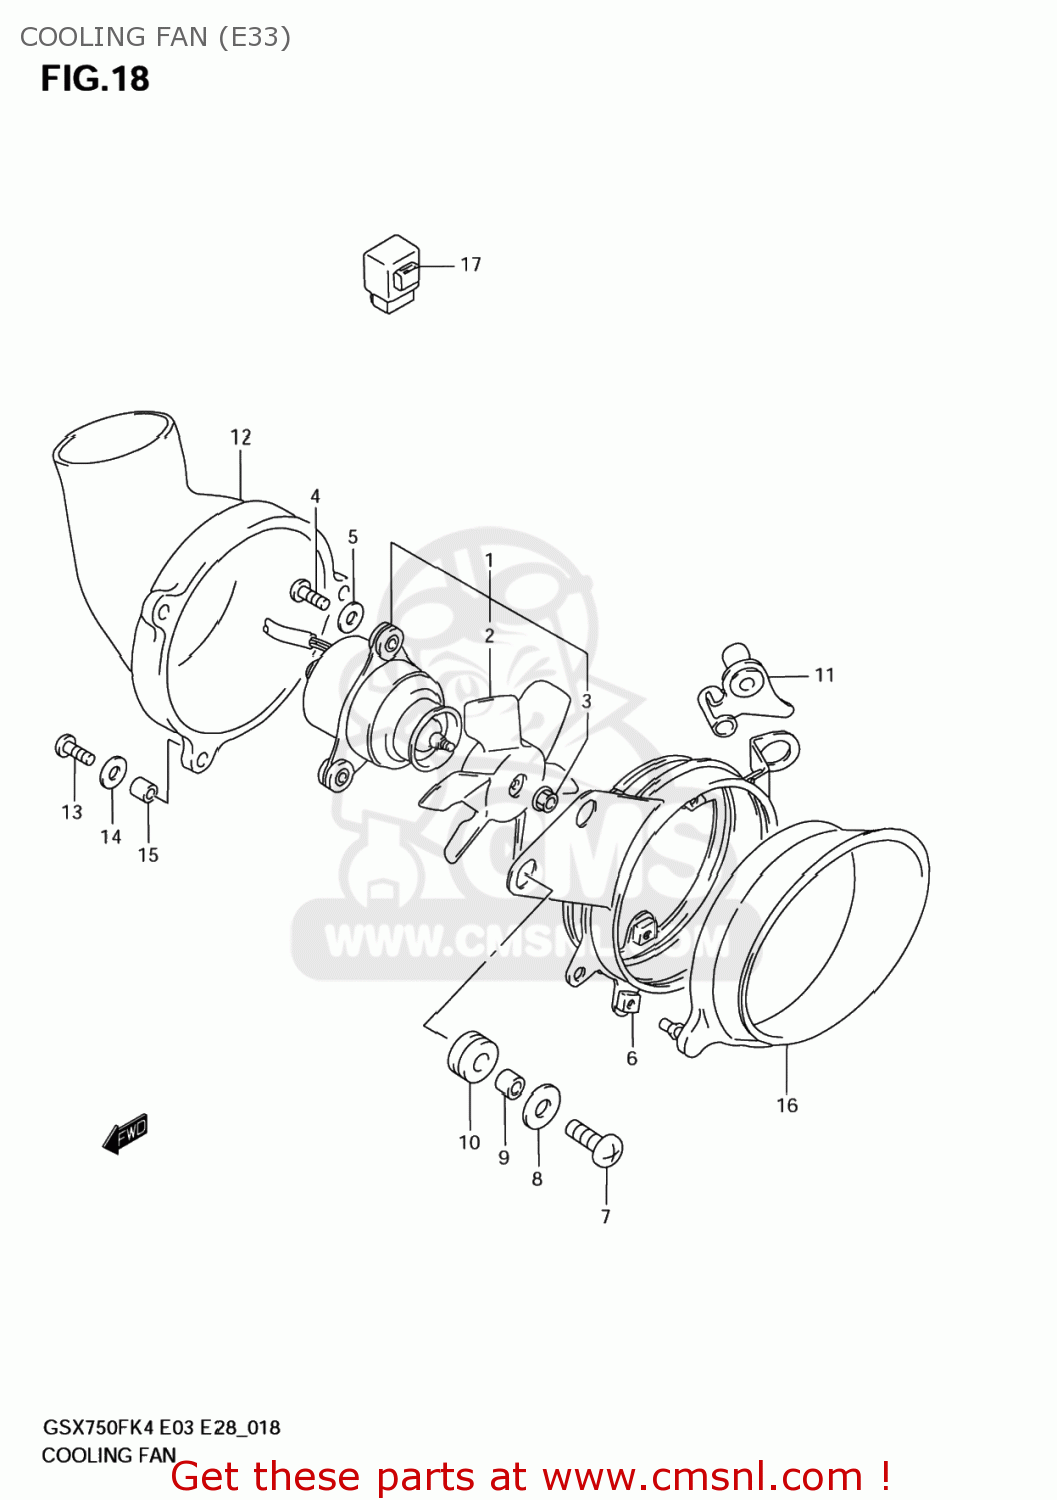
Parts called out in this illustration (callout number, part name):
1	FAN ASSY,COOLING
2	FAN
3	NUT
4	SCREW 4X16
5	WASHER(4.3X14X0.8)
6	SHROUD,FAN
7	SCREW
8	WASHER(6.5X18X1)
9	SPACER(6.5X9X6.5)
10	CUSHION
11	BRACKET,FAN SHROUD
12	DUCT,FAN COOLING NO.1
13	SCREW
14	WASHER(4.3X14X0.8)
15	SPACER(4.5X6.5X5)
16	DUCT,FAN COOLING NO.2
17	CONTROLLER ASSY,FAN MOTOR
